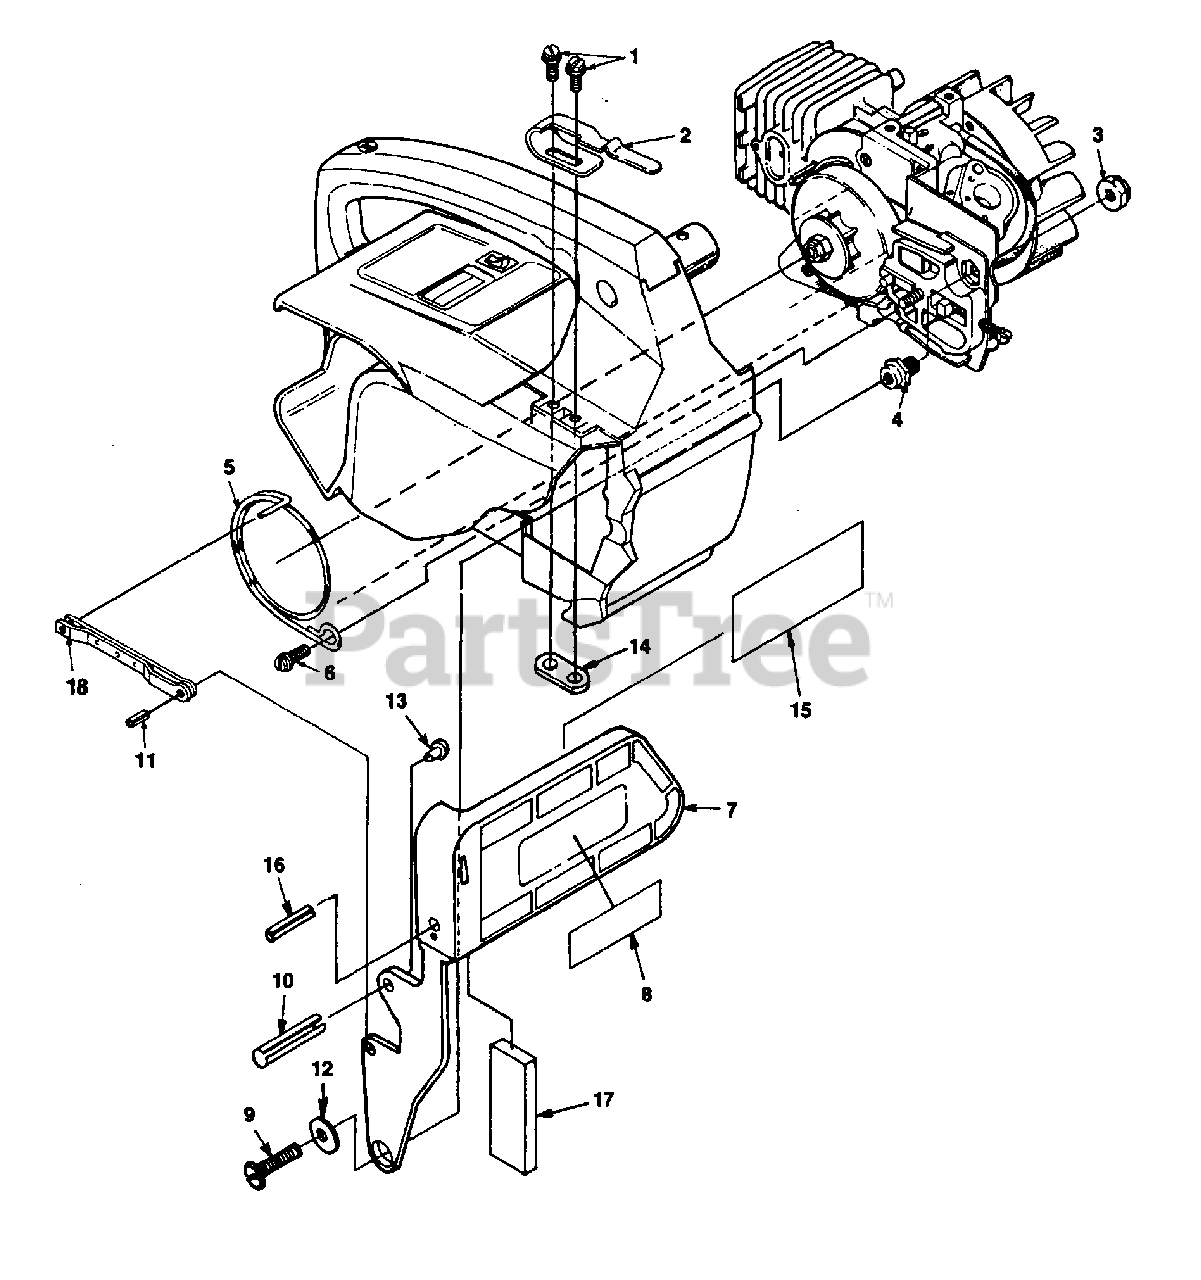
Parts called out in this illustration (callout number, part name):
1	SCREW- Hex hd. w/washer (8-32 x 1/2")
2	CLIP- Retaining
3	NUT- Hex
4	POST- Chain brake
5	BAND- Brake
6	SCREW- Torx (10-24 x 5/8")
7	HANDGUARD & LEVER
8	DECAL (International Only)
9	SCREW- (10-32 x 1/2")
10	PIN- Roll (3/16 x 1")
11	PIN- Spring
12	WASHER- Flat
13	SCREW- Drive
14	NUT- Weld
15	DECAL- Handguard
16	PIN- Roll (1/8 x 7/8") (International Only)
17	WEIGHT (International Only)
18	PIVOT- Link
